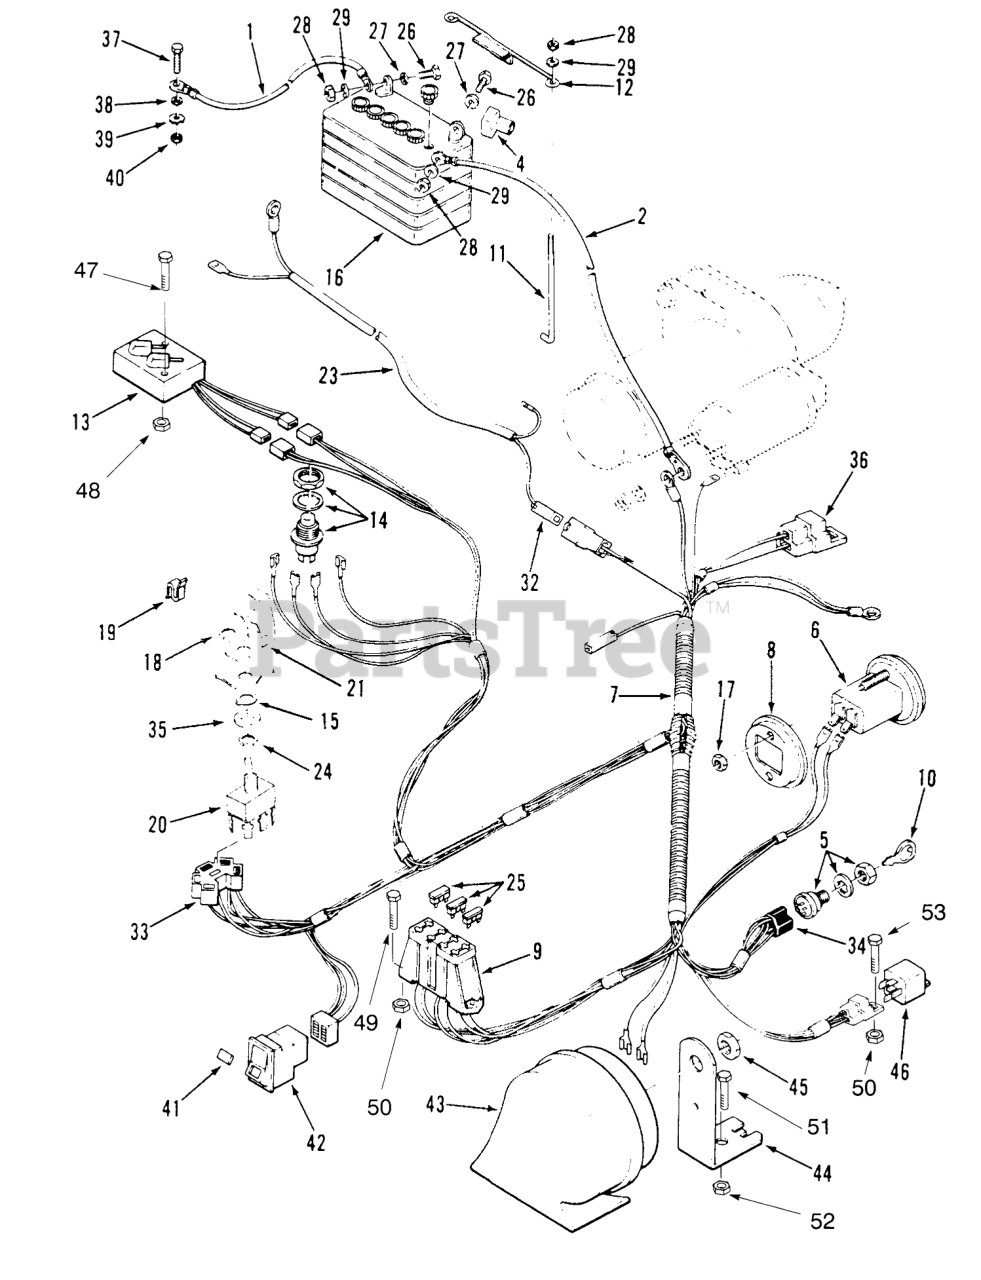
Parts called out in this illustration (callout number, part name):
1	WIRE -BLACK
2	ASS'Y-WIRE BATTERY
4	Boot
5	Switch-Ignition (Incl. Nut 101884 & Screw 103990)
6	Hourmeter (Incl. Ref. # 8)
7	Harness-Wiring (Incl. Ref.#9, 33, & 34)
8	CLAMP-HOUR METER
9	AUTO-FUSEBLOCK TERM
10	KEY-IGNITION
11	HOOK-BATTERY RETAIN
12	HOLDDOWN-BATTERY
13	SWITCH-ASS'Y NEUTRAL
14	SWITCH-PLUNGER
15	TAB-WASHER
16	Battery
17	NUT-HEX
19	CLIP-CABLE
20	SWITCH-TOGGLE, SEALED
21	COVER-PTO SWITCH
23	Harness-Wiring (Inc. Ref.#32)
24	NUT-HEX, SPECIAL
25	FUSE-BLADE, 15 AMP
26	SCREW-HH
27	WASHER-FLAT
28	NUT-WING
29	WASHER-LOCK
32	MALE CONNECTOR
33	Connector-PTO Switch
34	CONNECTOR-5 WAY-SERV
35	WASHER
36	CONNECTOR BODY
37	SCREW-HH
38	WASHER-FLAT
39	WASHER-LOCK
40	NUT-HEX
41	LENS-ENG TEMP
42	Switch-Test (Incl. Ref.#41)
43	Horn And Bracket Assembly (Inc. Ref.#44 & 45)
44	BRACKET-HORN
45	LOCKNUT
46	Relay
47	SCREW-PPH
48	NUT-KEPS
50	NUT-LOCK, NI
51	SCREW-HH
52	NUT-LOCK, NI
53	SCREW-SHWH
